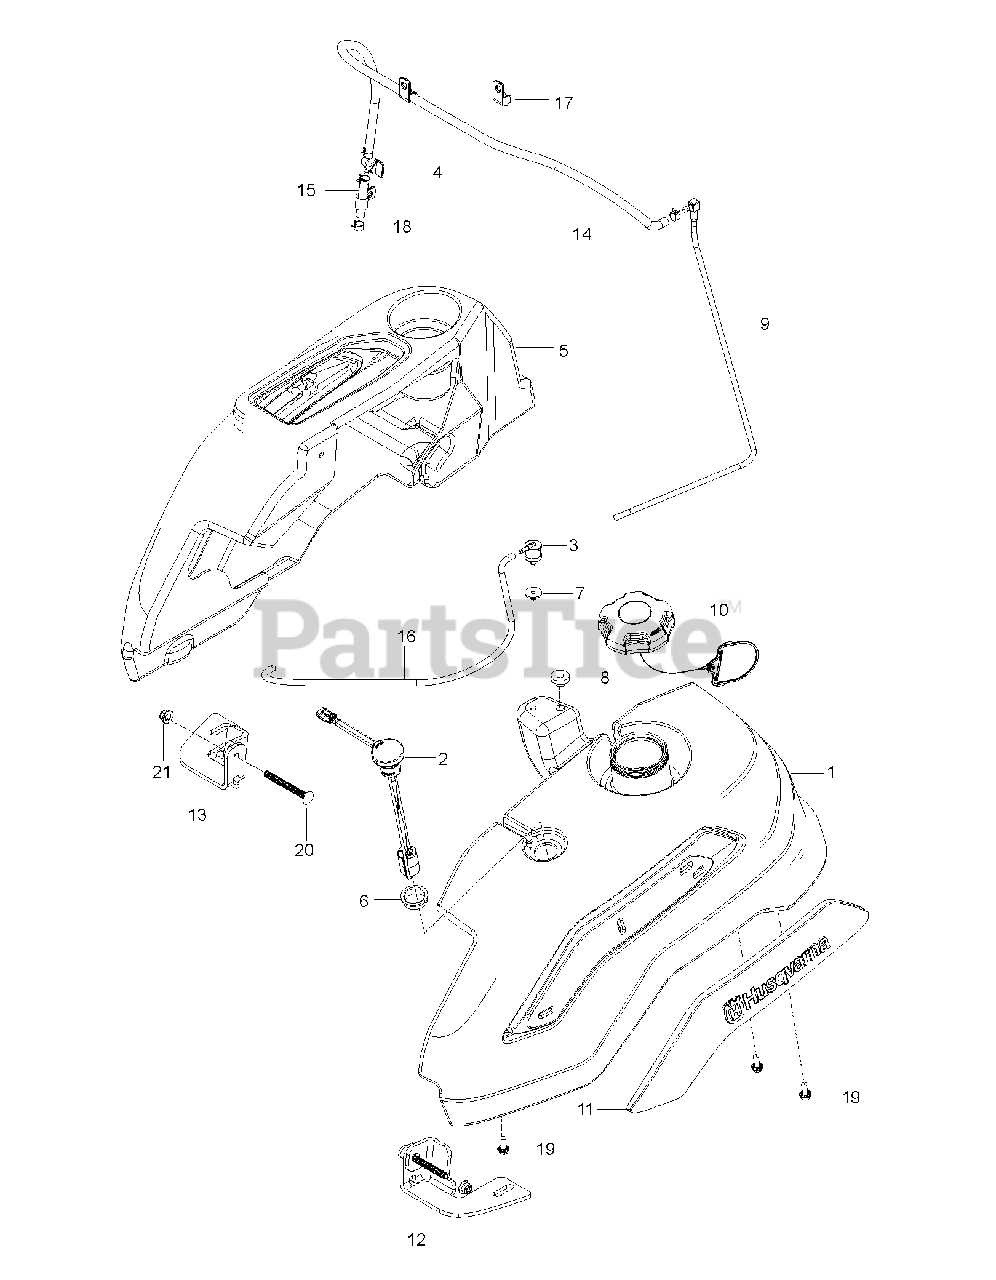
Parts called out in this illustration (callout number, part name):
1	TANK ASSY STAND-ON 2017 PRODUC
2	SENSOR.FUEL.LVL.FLOAT.V500
3	VALVE.FUEL.CHECK
4	FUEL VALVE
5	CONSOLE STAND-ON
6	GROMMET, FUEL SENSOR
7	Check Fuel Grommet
8	BUSHING OUTLET T
9	VALVE.ASM.P-UP.W/SHUTOFF.STNDN
10	CAP, FUEL
11	Fuel Tank Cover, LH Console App
11	COVER.RH.FUEL.TANK/CONSOLE APP
12	FRONT MOUNTING BRACKET, LH
13	FRONT MOUNTING BRACKET, LH
14	HOSE.1/4".LOW.PERM.FUEL.LN.37"
15	HOSE.1/4".LOW.PERM.FUEL.LN.5"
16	HOSE.3/16".VAPOR.LINE.21"LGTH
18	HOSE CLAMP
19	BOLT 5/16-18 X .75 HEX FLANGE
21	NUT 3/8-16 HEX FLG NYLOC ZD
